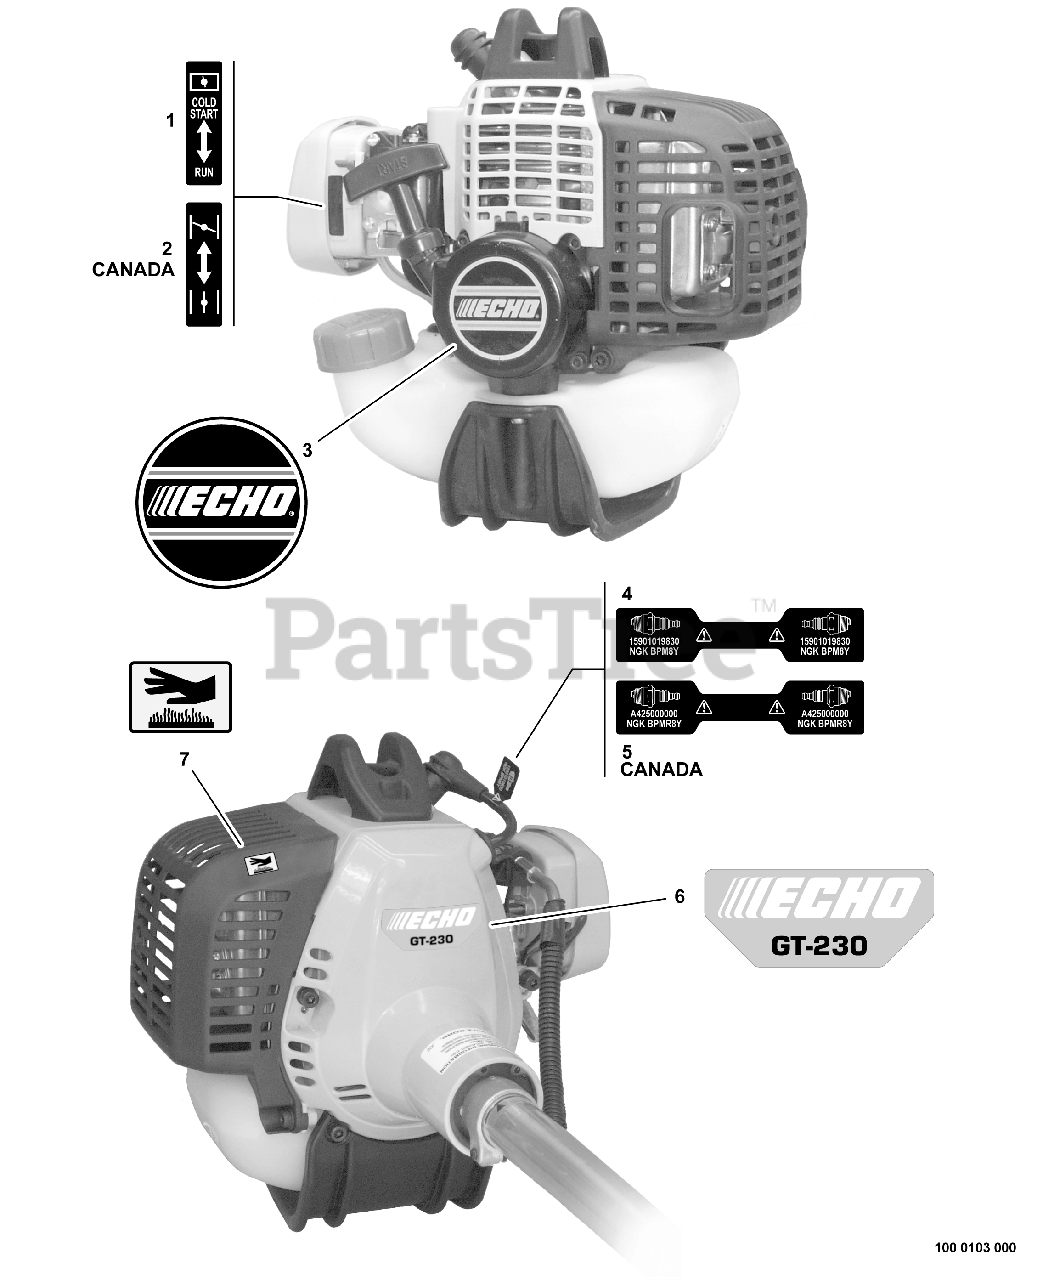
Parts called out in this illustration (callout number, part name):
1	LABEL - CHOKE
2	LABEL - CHOKE
3	LABEL - ECHO
4	LABEL - SPARK PLUG -- BPM-8Y
5	LABEL - SPARK PLUG -- BPMR-8Y
6	LABEL - MODEL GT-230
8	LABEL - HOT SURFACE
